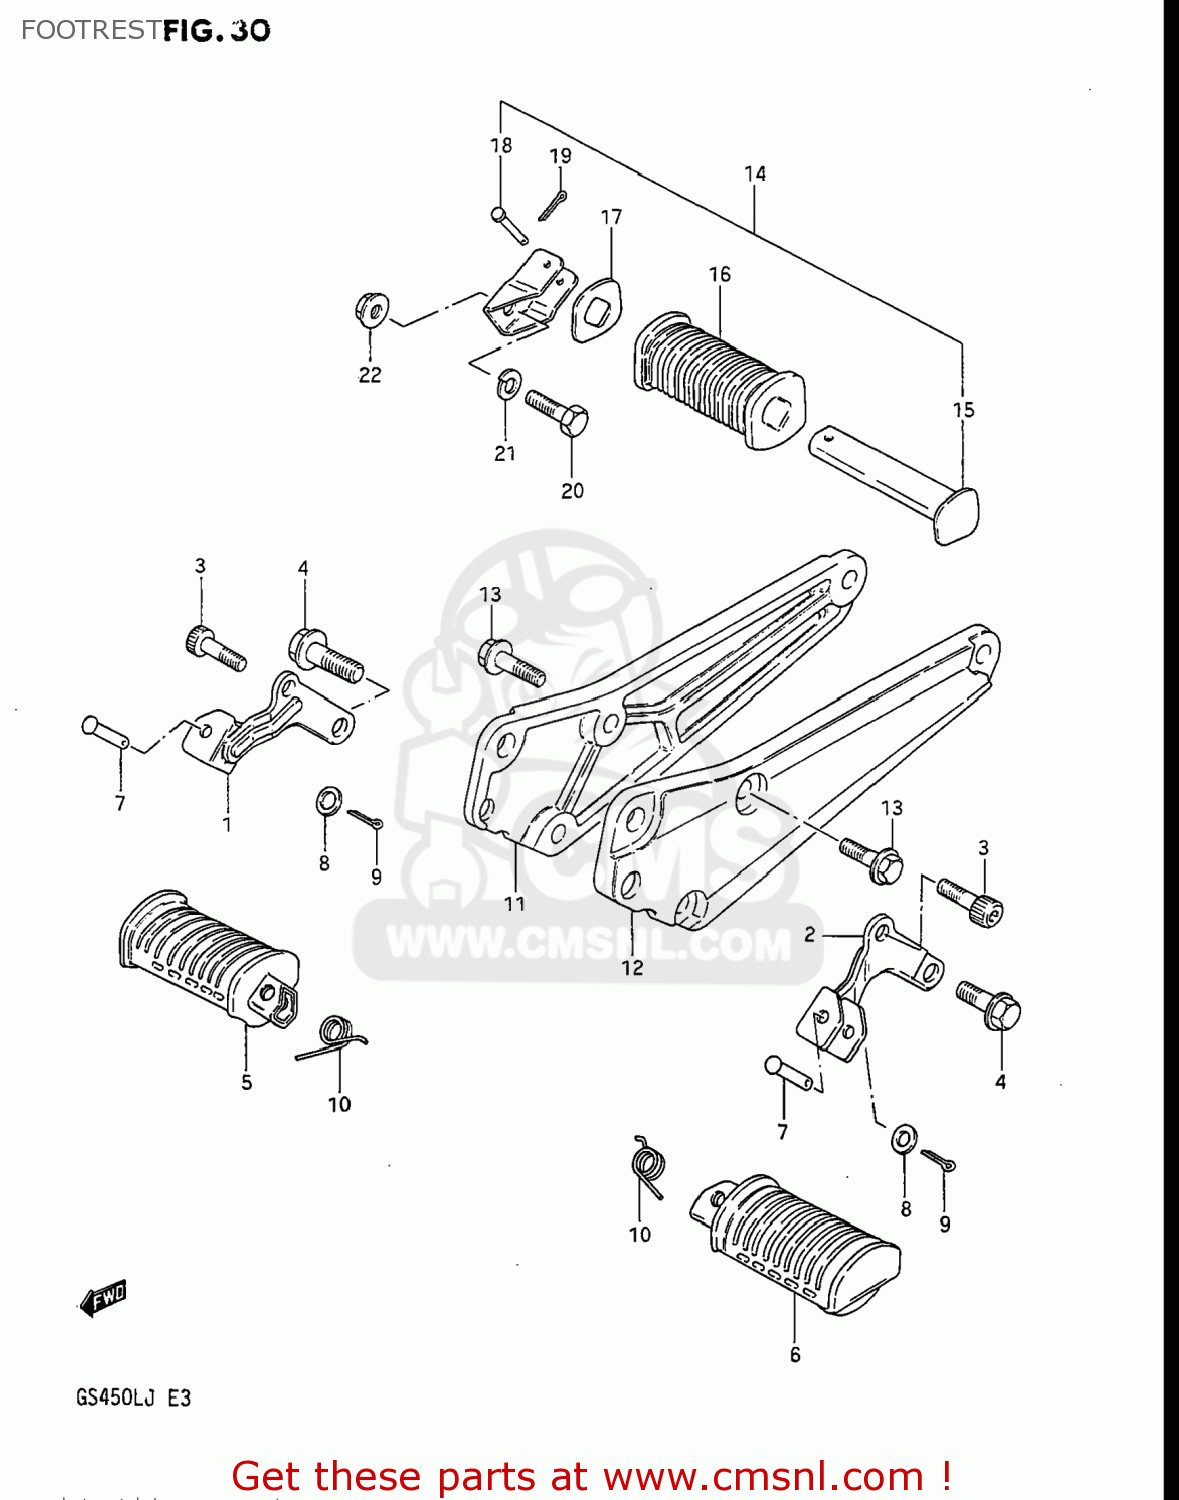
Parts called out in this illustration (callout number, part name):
1	BAR,FRONT FOOTREST,RIGHT
2	BAR,FRONT FOOTREST,LEFT
3	BOLT
4	BOLT
5	RUBBER,PILLION FOOTREST,R
6	RUBBER,PILLION FOOTREST,L
7	PIN
8	WASHER
9	PIN 20X20
10	SPRING
11	BRACKET,MUFFLER,RIGHT
12	BRACKET,MUFFLER,LEFT
13	BOLT
14	FOOTREST ASSY,PILLION,R
15	BAR,REAR FOOTREST,LEFT
16	RUBBER,PILLION FOOTREST
17	WASHER,FOOTREST RUBBER
18	PIN
19	PIN 20X20
20	BOLT,M10X1.25X
21	WASHER,LOCK,10
22	NUT
